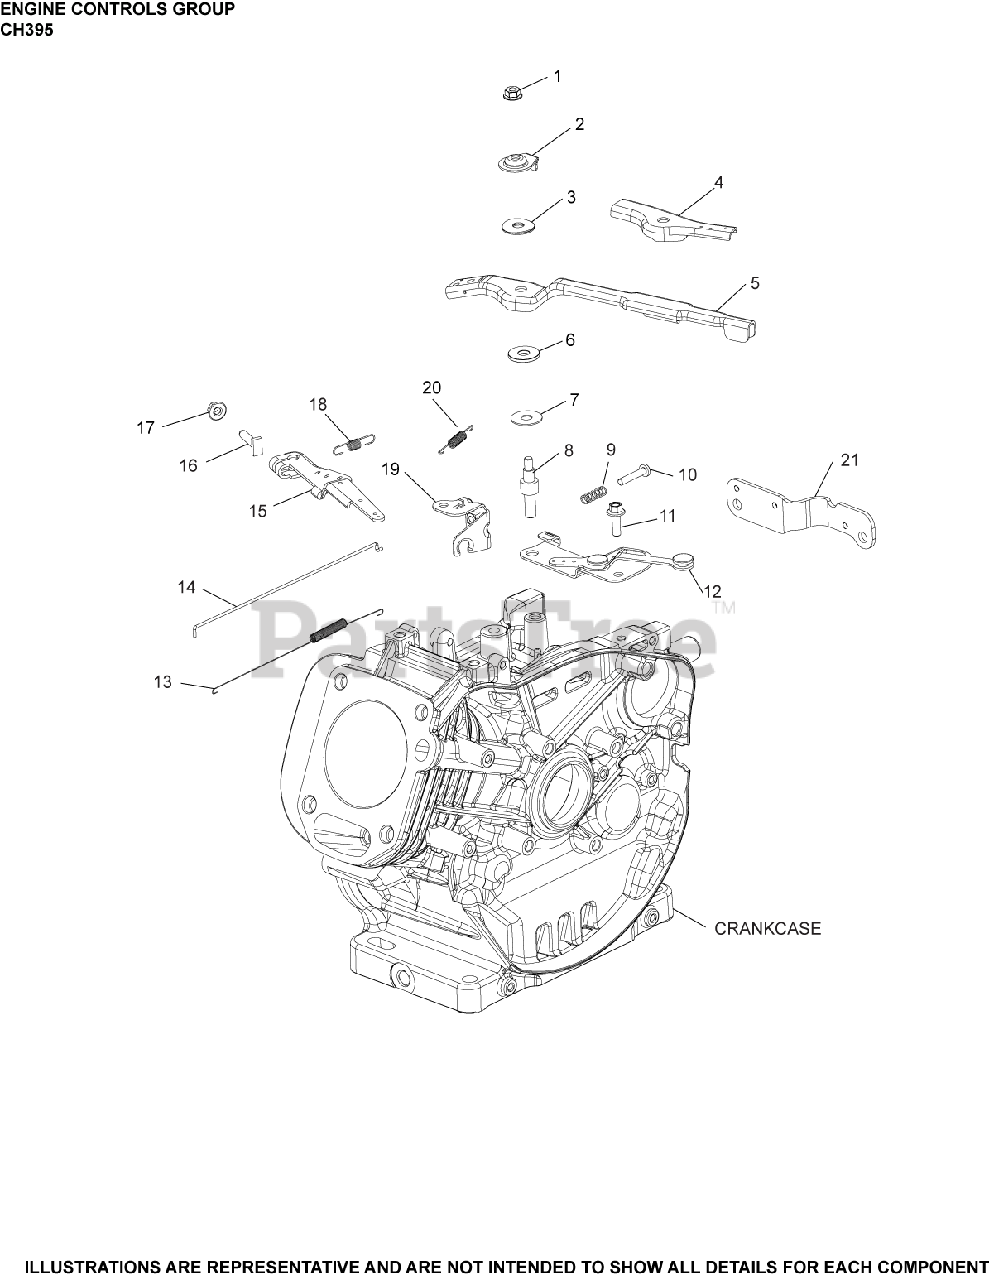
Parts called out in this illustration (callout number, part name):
1	NUT, HEX FLANGE LOCK (M6)
2	WASHER, CONTROL LEVER
5	CONTROL LEVER ASSEMBLY
6	WASHER, NYLON CONTROL LEVER
7	WASHER, FLAT
8	STUD, CONTROL LEVER
9	SPRING, COMPRESSION
10	SCREW, SPEED ADJUSTING
11	SCREW, M6 X18
12	BRACKET, CONTROLS ASSY
13	SPRING, LINKAGE
14	LINKAGE, GOVERNOR
15	KIT, GOVERNOR LEVER USE 17 090 54-S
16	SCREW, RECTANGLE HEAD (M6)
17	NUT, HEX FLANGE (M6) - USE 14 100 16-S
18	SPRING, GOVERNOR
20	SPRING, THROTTLE RETURN
